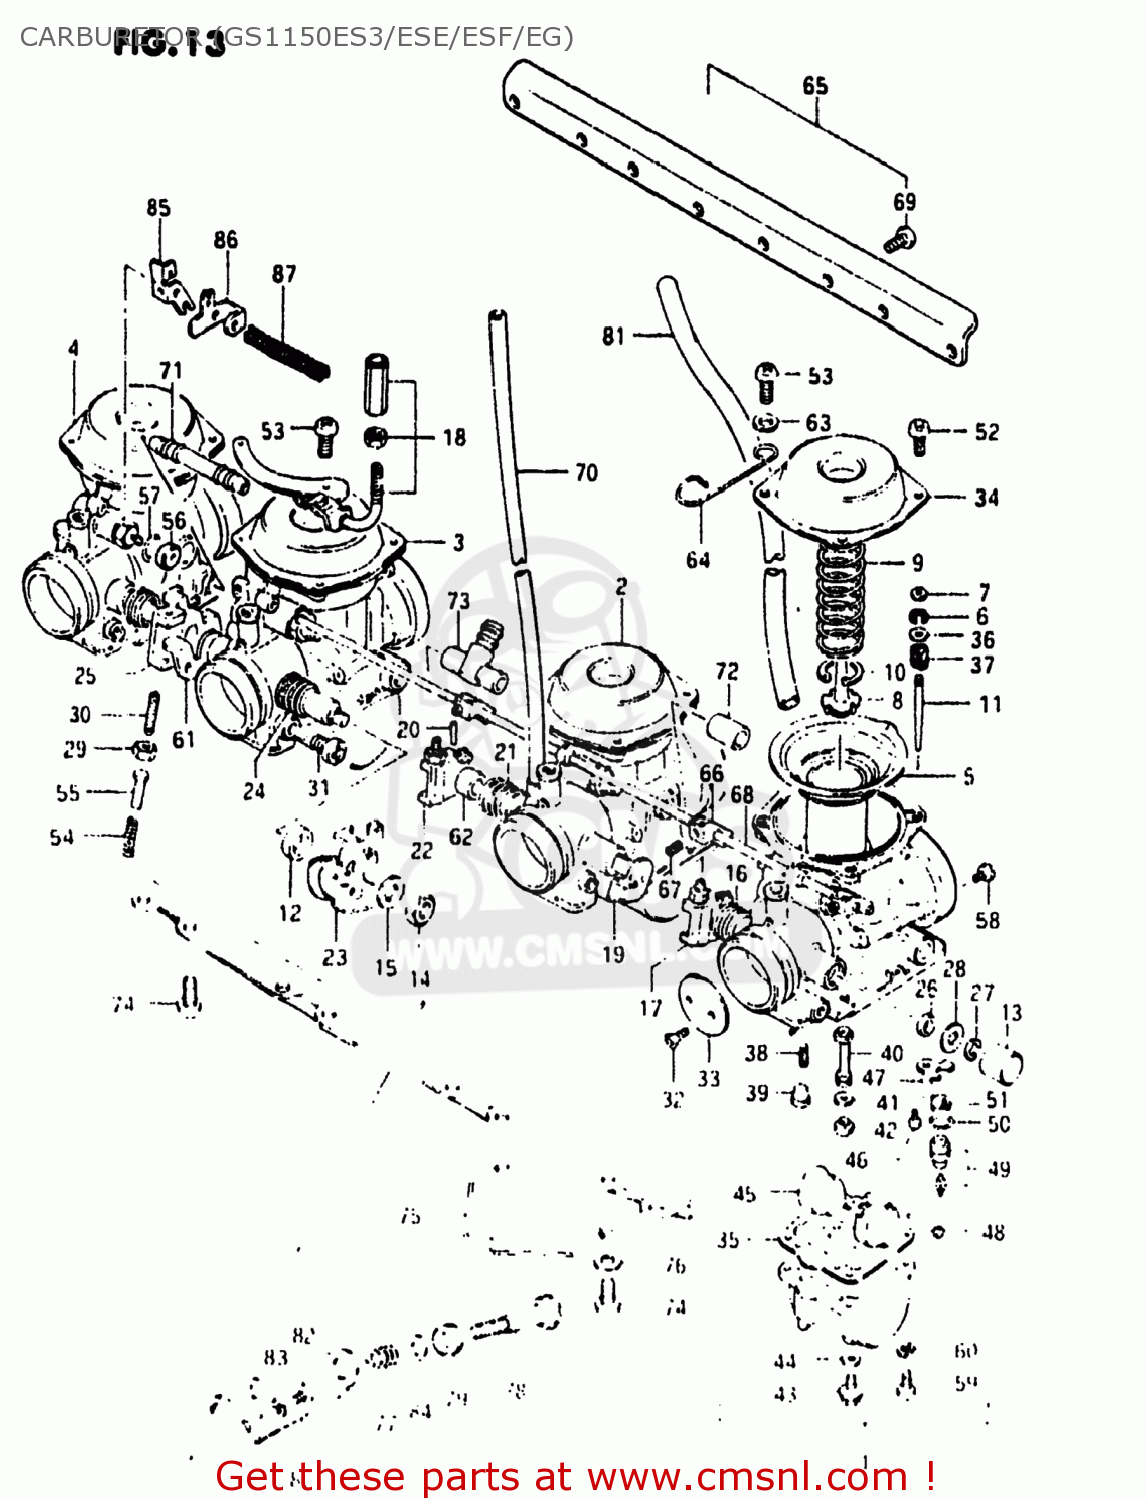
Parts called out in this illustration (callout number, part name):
1	CARBURETOR,LEFT
2	CARBURETOR,MIDDLE,LEFT (AS
3	CARBURETOR ASSEMBLY
4	CARBURETOR,RIGHT
5	DIAPHRAGM,CARBURETOR
6	CLIP,NEEDLE
7	RING
8	HOLDER,GUIDE
9	SPRING
10	E RING
11	NEEDLE JET
12	GASKET
13	CAP,THROTTLE SHAFT
14	NUT
15	WASHER
16	SPRING,THROTTLE SHAFT
17	SHAFT,THROTTLE
18	BRACKET
19	SHAFT,THROTTLE
20	PIN,THROTTLE SHAFT
21	SPRING,THROTTLE SHAFT
22	LEVER,THROTTLE SHAFT
23	LEVER ASSEMBLY,THROTTLE
24	SPRING,THROTTLE SHAFT
25	SHAFT,THROTTLE
26	SEAL
27	E RING
28	GASKET,THROTTLE SHAFT (NAS)
29	NUT
30	SCREW
31	SCREW
32	SCREW
33	VALVE
34	COVER,DIAPHRAGM
35	GASKET,FLOAT CHAMBER (NAS)
36	WASHER
37	SPRING
38	JET,PILOT(45)
39	PLUG,NEEDLE JET
40	JET,NEEDLE
41	WASHER,NEEDLE NOZZLE
42	JET,MAIN(120)
43	PLUG,DRAIN
44	GASKET (NAS)
45	FLOAT
46	SCREW
47	PLATE,NEEDLE VALVE FITING
48	PIN,FLOAT
49	VALVE ASSEMBLY,NEEDLE
50	O-RING,NEEDLE VALVE
51	FILTER
52	SCREW
53	SCREW
54	SPRING,THROTTLE SCREW
55	PIN,THROTTLE LEVER
56	CAP,STARTER VALVE
57	O RING
58	JET,AIR
59	SCREW
60	WASHER,LOCK
61	SHAFT,THROTTLE
62	SPACER,THROTTLE SHAFT
63	WASHER
64	CLIP
65	CARBURETOR ASSEMBLY
66	LEVER
67	SCREW
68	SHAFT,STARTER
69	SCREW
70	HOSE
71	NIPPLE
72	HOSE
73	NIPPLE
74	SCREW
75	CLIP
76	WASHER
77	SPRING
78	ADJUSTER
79	BUSH
80	BRACKET
81	HOSE
82	SCREW
83	WASHER,LOCK
84	WASHER
85	LEVER
86	LEVER
87	SPRING
